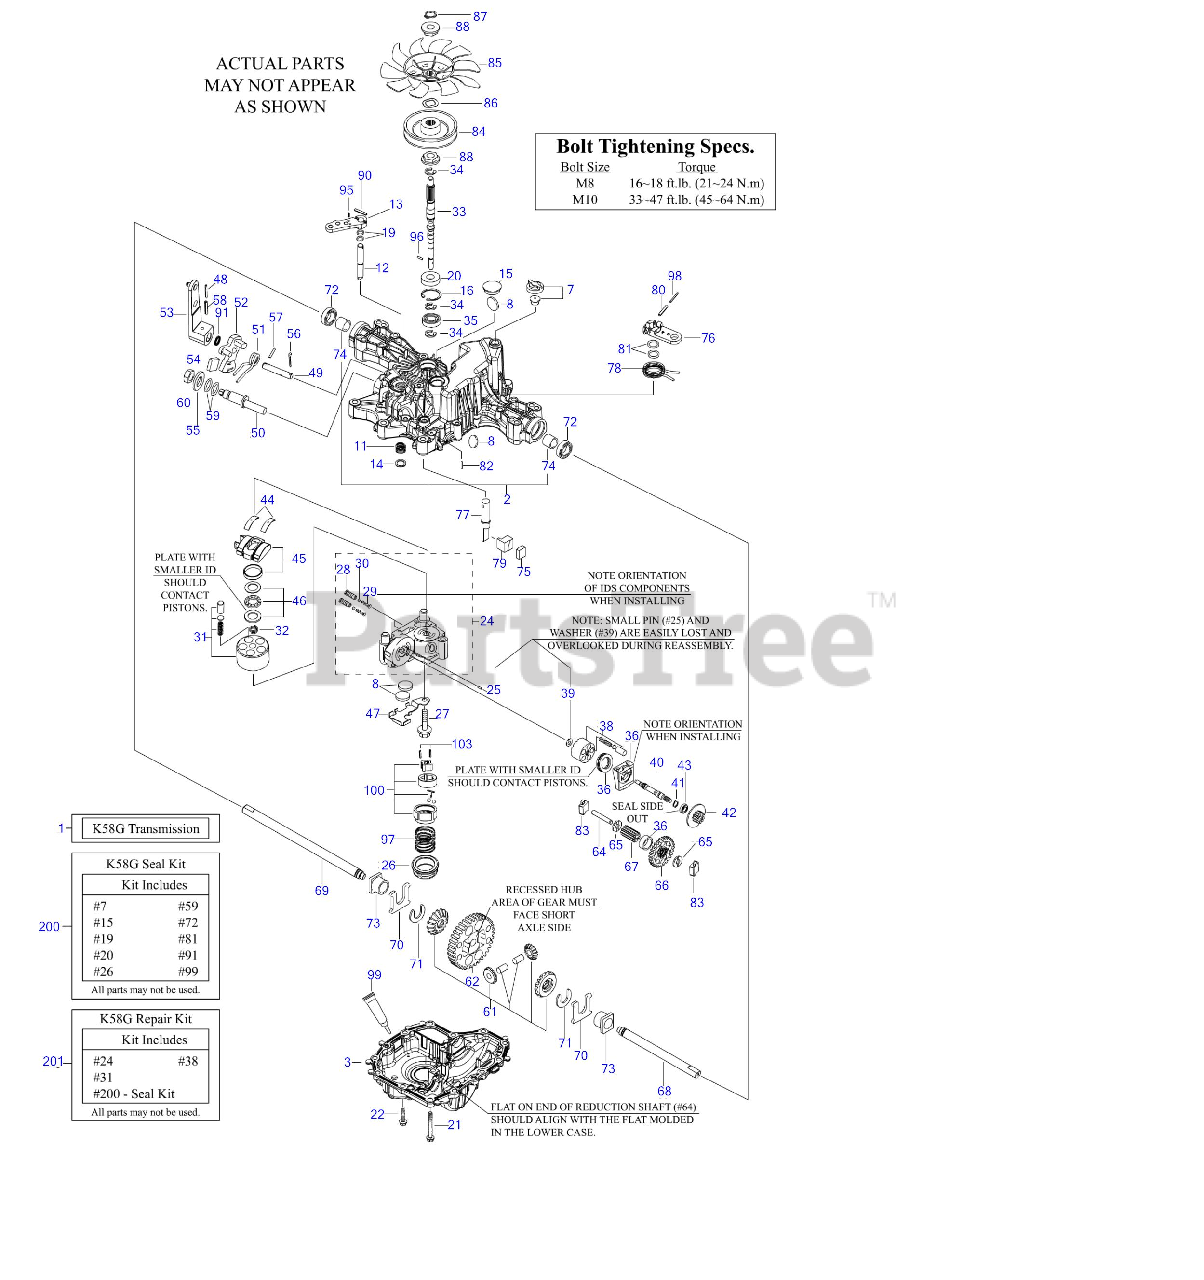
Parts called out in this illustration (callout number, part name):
1	TRANSMISSION K58G
2	UPPER HOUSING ASSY
8	MAGNET 28 * 3.5
12	BYPASS SHAFT A
15	SEALING CAP, STEEL
16	SNAP RING C 35
19	0-RING 1A P10A
21	TAPPING SCREW 8 * 55
22	TAPPING SCREW 8 * 30
24	CENTER CASE H/FILTER IDS SERVICE KIT
28	IDS VALVE 1.2
30	IDS FILTER 300
31	CYLINDER BLOCK KIT
35	BEARING
37	THRUST BALL BEARING
38	CYLINDER BLOCK KIT(MOTOR
39	WASHER 12 * 24 * 1
41	SNAP RING S15
42	MOTOR GEAR (11T)
43	BEARING 6202RSSH2-9TC3
44	THRUST BUSHING
45	SWASH PLATE CMP
46	THRUST BEARING (PUMP) KIT
47	MAGNET HOLDER
48	ROLL PIN 3.5 * 40
49	CONTROL SHAFT
51	TORSION SPRING
52	CONTROL ARM A
53	CONTROL LEVER F
56	COTTER PIN 1/8" * 3/4"
57	SPRING PIN 6 * 36
58	ROLL PIN 6 * 40
59	O-RING 1A P14
61	DIFF GEAR KIT
64	REDUCTION SHAFT
65	WASHER 12 * 32 * 3.2
66	REDUCTION GEAR
68	AXLE SHAFT LEFT
69	AXLE SHAFT RIGHT
70	THRUST WASHER
71	RETAINING RING 23
72	AXLE OIL SEAL
78	BRAKE RETURN SPRING
79	BRAKE ACTUATOR
80	SPRING PIN 5 * 32
81	O-RING 1A P12
82	SPRING PIN 4 * 16
83	SUPPORT BUSHING
88	SPLINE COLLAR
90	SPRING PIN 3.0A * 20
91	OIL SEAL 16 * 22 * .03
95	SPRING PIN 3.0A * 16
97	CHARGE SPRING
100	CHARGE PUMP KIT
200	SEAL KIT
201	REPAIR KIT
